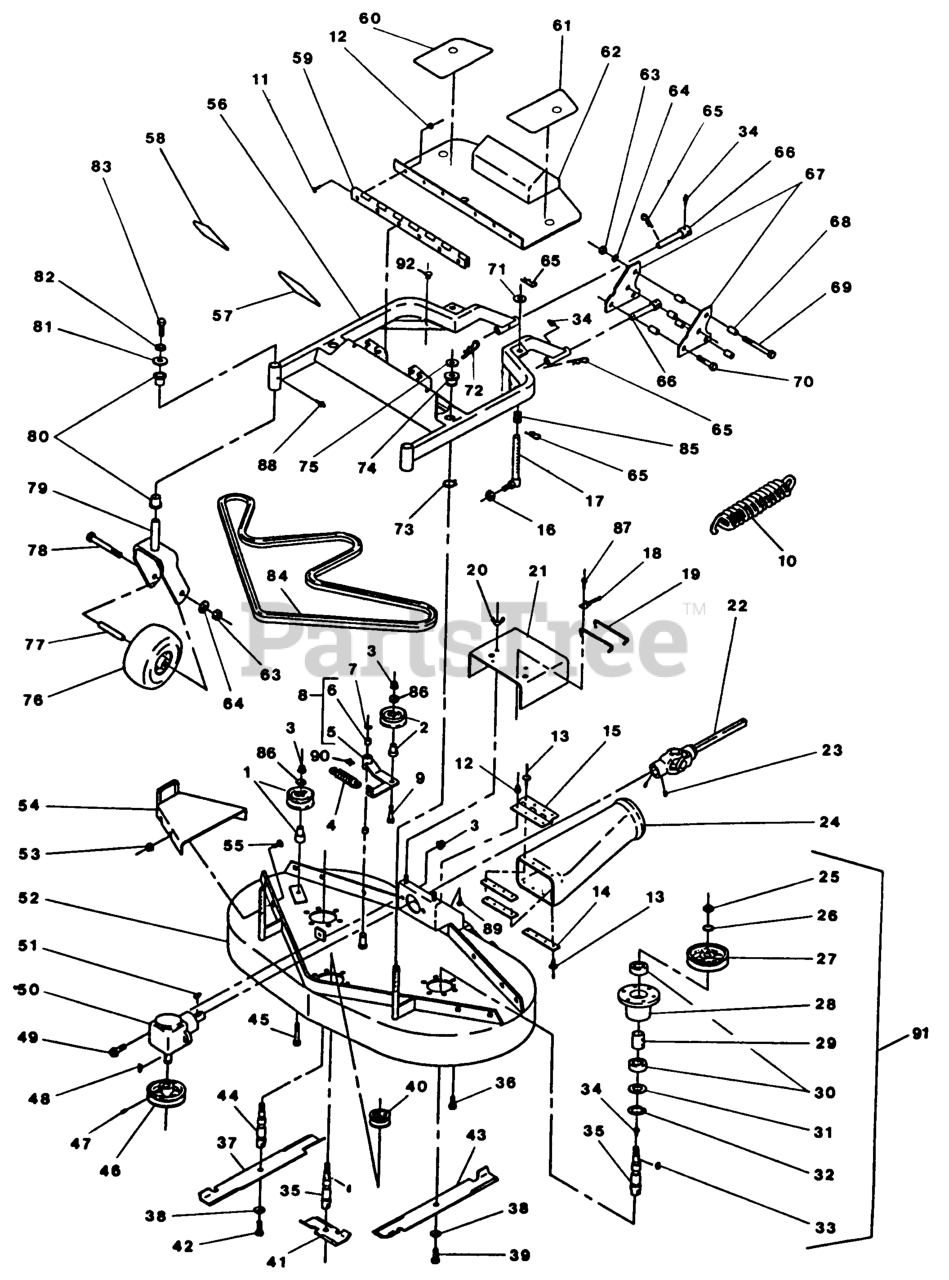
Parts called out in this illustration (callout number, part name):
1	KIT,IDLER & BUSHING
6	SLEEVE-BEARING
18	CLIP-DECK, HOLD UP ROD
20	WINGNUT-NYLOCK
22	PTO SHAFT,SHAFT HALF PNT
26	WASHER-SPRING
27	SHEAVE,BLADE DRIVE
29	SPACER,BEARING
31	SEAL,MECHANICAL DUST
32	RING,SNAP WLDS N5000-244
38	WASHER-SPRING
42	SCREW-CAP,HH
47	SCREW-SET
50	GEARBOX, PEERLESS
57	PAD,ANTI SKID UPPER LH
58	PAD,ANTI SKID UPPER RH
59	HINGE,FLOORPAN
60	PAD,ANTI SKID LOWER RH
65	PIN,HAIR COTTER
66	PIVOT - MOUNTING, W/ZERK
74	BUSHING-DECK
75	WASHER-FLAT
80	BEARING-FLANGED
85	SPRING,HITCH RELEASE
87	Pop Rivet, Steel 3/16 X .250
89	BOLT-CARR
